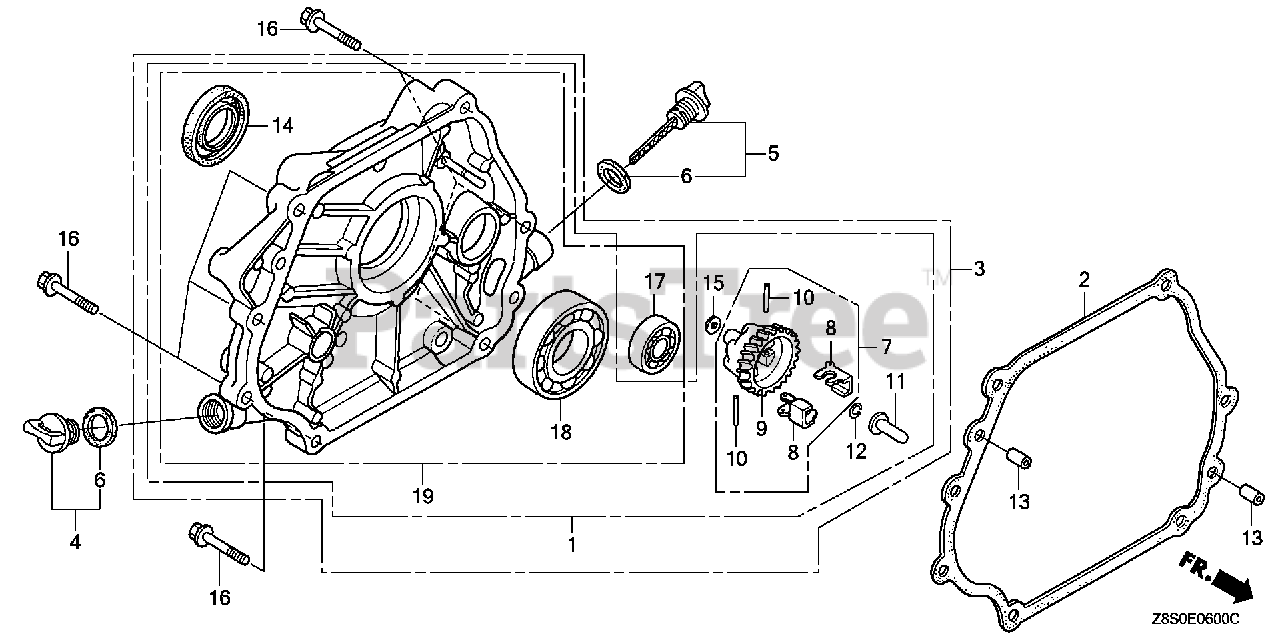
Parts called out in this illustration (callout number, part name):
1	COVER ASSY., CRANKCASE
2	GASKET, CASE COVER
4	CAP ASSY., OIL FILLER (BLACK)
5	CAP ASSY., OIL FILLER
6	GASKET, OIL FILLER CAP
7	GOVERNOR ASSY.
8	WEIGHT, GOVERNOR
9	HOLDER, GOVERNOR WEIGHT
10	PIN, GOVERNOR WEIGHT
11	SLIDER, GOVERNOR
12	CLIP, GOVERNOR HOLDER
13	PIN, DOWEL (8X12)
14	OIL SEAL (30X46X8) (NOK ASIA)
15	WASHER, PLAIN (6MM)
16	BOLT, FLANGE (8X35)
18	BEARING, RADIAL BALL (6206)
